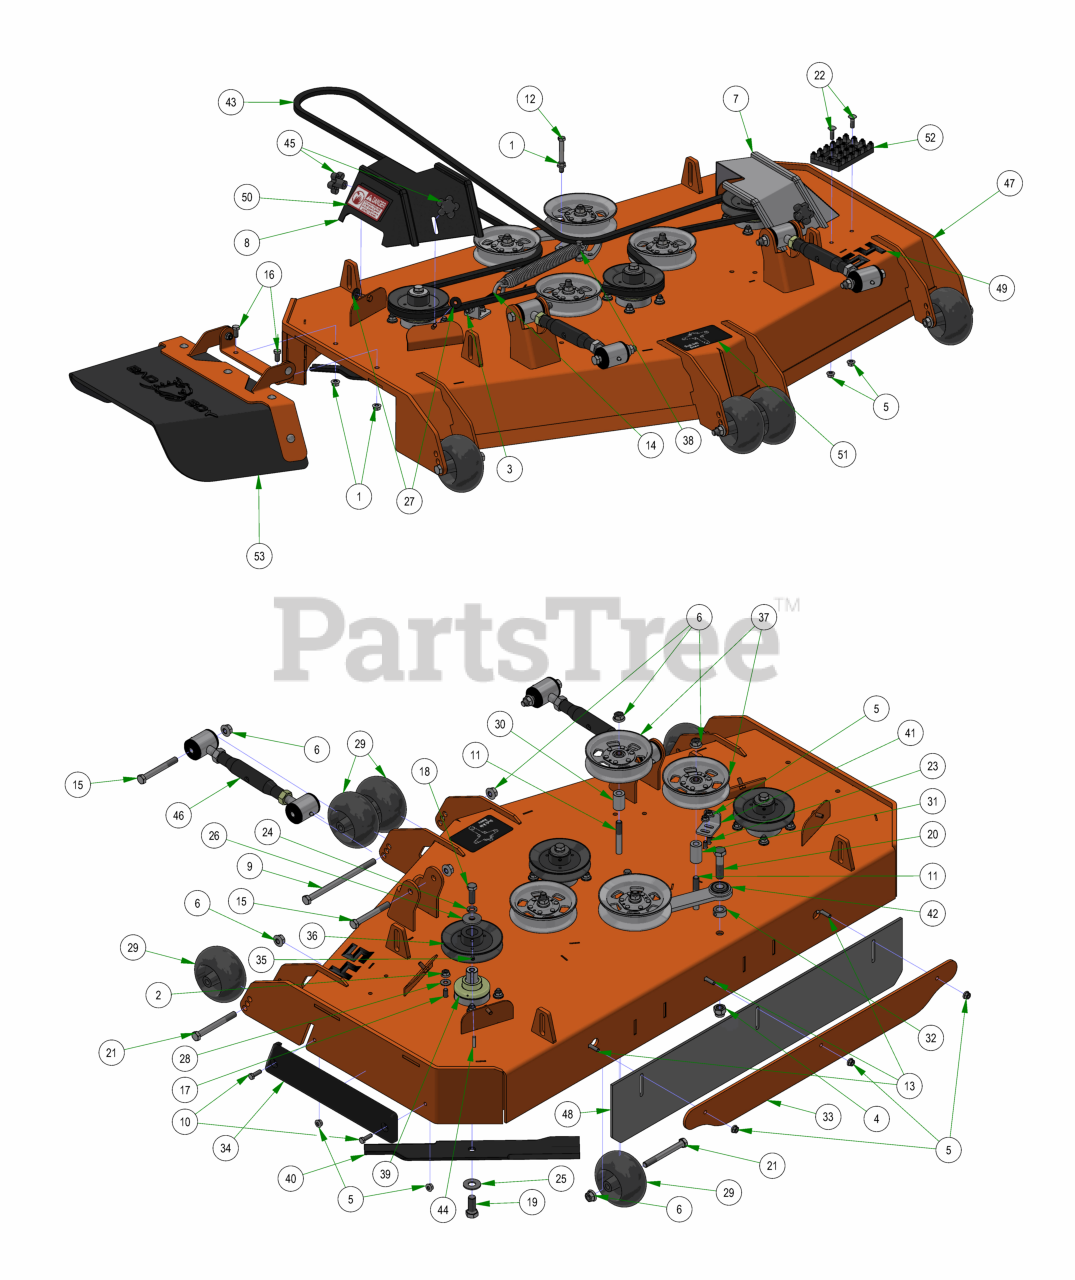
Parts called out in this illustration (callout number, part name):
1	3/8-16 HEX SERRATED FLANGE NUT HARD/ZINC
2	3/8-16 NYLON INSERT FLANGE LOCKNUT (GR.F) ZINC
3	3/8-16 HEX NUT ZINC
4	5/8-11 NYLON INSERT LOCKNUT ZINC
5	5/16-18 NYLON INSERT FLANGE LOCKNUT ZINC
6	1/2-13 NYLON INSERT FLANGE LOCKNUT ZINC
7	2019 54" Left Outlaw Gen2 Pulley Cover
8	2019 54" Right Outlaw Gen2 Pulley Cover
9	1/2-13 X 8 HEX CAP SCREW GR 5 ZINC
10	5/16-18 X 1 HEX CAP SCREW (GR.5) ZINC
11	1/2-13 X 3-1/2 HEX FLANGE BOLT (GR.8) ZINC
12	3/8-16 X 3 HEX CAP SCREW (GR.5) ZINC
13	5/16-18 X 1-1/4 CARRIAGE BOLT ZINC
14	4" 3/8-16 Eye Bolt
15	1/2-13 X 4 HEX CAP SCREW (GR.8) ZINC YELLOW
16	3/8-16 X 3/4 HEX CAP SCREW (GR.5) ZINC
17	3/8-16 X 1-1/2 HEX CAP SCREW (GR.5) ZINC
18	1/2-20 X 1-1/2 HEX CAP SCREW (GR.5) ZINC
19	5/8-18 X 1-1/2 HEX CAP SCREW (GR.8) ZINC YELLOW
20	5/8-11 X 2-1/2 HEX CAP SCREW (GR.5) ZINC
21	1/2-13 X 4-1/2 HEX CAP SCREW (GR.5) ZINC
22	5/16-18 X 1 CARRIAGE BOLT (GR.8) ZINC
23	5/16-18 X 7/8 CARRIAGE BOLT ZINC
24	1/2 SPLIT LOCKWASHER (GR.8) ZINC/YELLOW
25	5/8 USS FLAT WASHER (1-3/4" OD) GR.8 ZINC YELLOW
26	1/2 BELLEVILLE WASHER (1-5/8 OD X .140 THK) ZINC
27	.360 ID X .983 OD X .120 THICK FLAT WASHER NYLON BLACK
28	5/16 USS FLAT WASHER (7/8 OD) ZINC
29	2019 Deck Wheel
30	.502 ID X .750 OD X 1.500 Long Spacer
31	1 3/4" Pulley Spacer
32	5/8 SOLID SHAFT COLLAR (W/1 SET SCREW) ZINC
33	61 Bolt in Baffle Deck v2 Stripping Plate
34	REVISED TRIM BUMPER_20180226
35	5/16-24 X 1/4 SOCKET SET SCREW (CUP PT) PLAIN
36	5.25" Deck Spindle Pulley
37	5-3/4 Idler Pulley
38	2019 Outlaw Gen2 Deck Spring
39	OUTLAW SPINDLE ASSEMBLY
40	54" Fusion Blade for ZT/Mav/Outlaw/Revolt
41	2019 Deck Eye Bolt Tab
42	2019 Rebel Rogue Deck Idler
43	B165 Belt-60 54" deck Outlaw
44	1/4 X 1 SQ MACHINERY KEY 1018 STL PLN
45	5/16" Knob
46	Turnbuckle Assembly (M20-2.5)
47	2019 Sloped 54" Deck
48	R Series Rubber For Deck
49	54" Deck Decal
50	Danger Decal-Spindle/Discharge
51	2019 Rebel & Rogue Deck Belt Route Decal
52	Deck Step Assembly
53	2019 Outlaw Gen2 Chute Assembly
